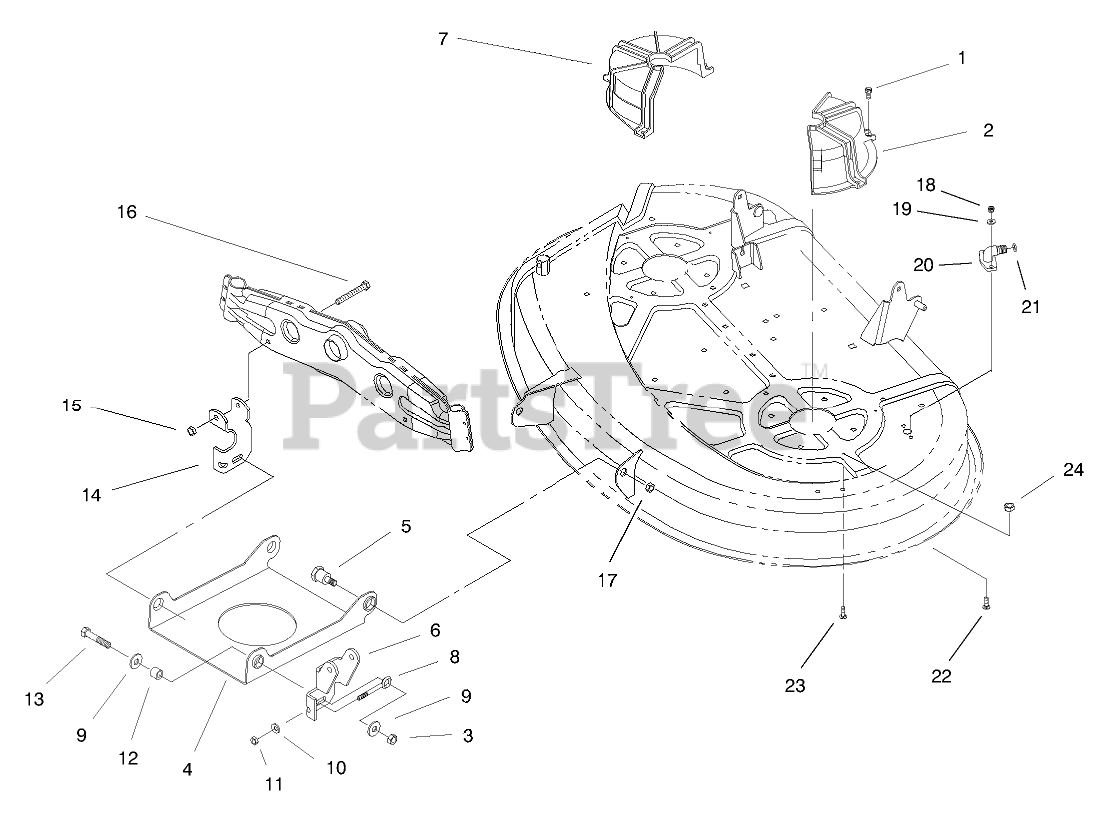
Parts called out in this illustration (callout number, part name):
1	SCREW-HWHTF
2	GUIDE-BELT, LH
3	NUT-LOCK, NI
4	PAN-DECK SUSPENSION, FRONT
5	BOLT-SHOULDER, HH
6	BRACKET-SUSPENSION, LH
7	GUIDE-BELT, RH
8	SCREW-ADJUSTING
9	WASHER-HARDENED
10	WASHER-FLAT
11	NUT-LOCK, NI
12	SPACER
13	SCREW-HH
14	BRACKET-SUSPENSION, RH
15	NUT-LOCK, NI
16	SCREW-HH
17	NUT-LOCK, NI
18	NUT-LOCK, NI
19	WASHER-FLAT
20	FITTING-WASHOUT
21	O-RING
22	BOLT-CARR
23	SCREW-HH
24	NUT-LOCK, NI
